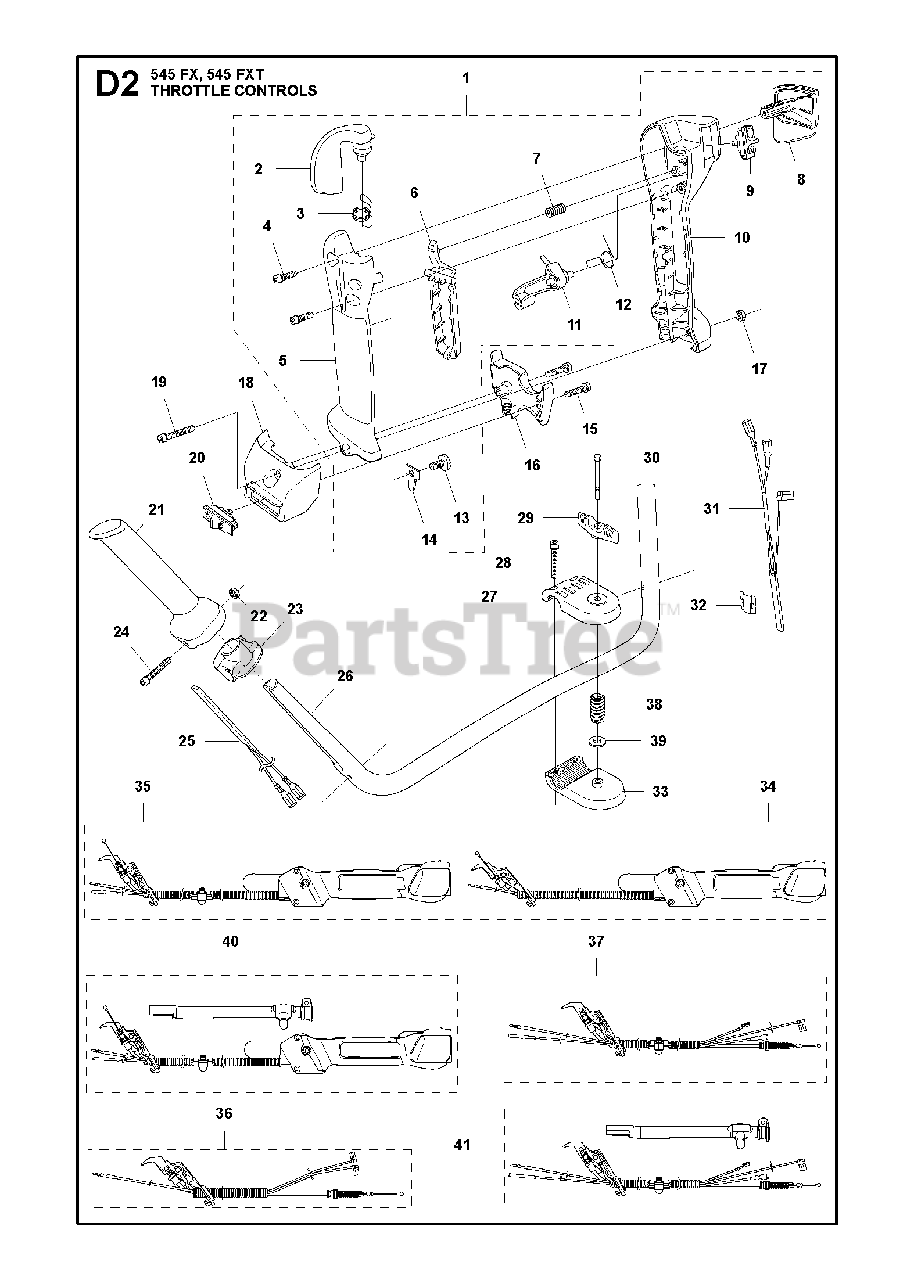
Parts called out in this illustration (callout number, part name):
1	THROTTLE HANDLE
2	THROTTLE TRIGGER
3	RP SPRING
4	SCREW
5	HANDLE
6	THROTTLE LOCK
7	SPRING
8	COVER
9	STOP BUTTON
10	HANDLE
11	LEVER
12	SPRING
13	SCREW
14	HOLDER
15	SCREW
16	HOLDER
17	NUT M6M M5
18	HOLDER
19	SCREW
20	SWITCH (G)
22	NUT M6M M5
25	HEATING ELEMENT
26	RP HANDLE
26	%HANDLE
27	HANDLE HOLDER UPPER
31	HEATING ELEMENT
32	HOLDER
33	HANDLE HOLDER LOWER
34	THROTTLE HANDLE ASSY HVA
35	THROTTLE HANDLE ASSY HVA HEAT
36	WIRING ASSY
37	WIRING ASSY
